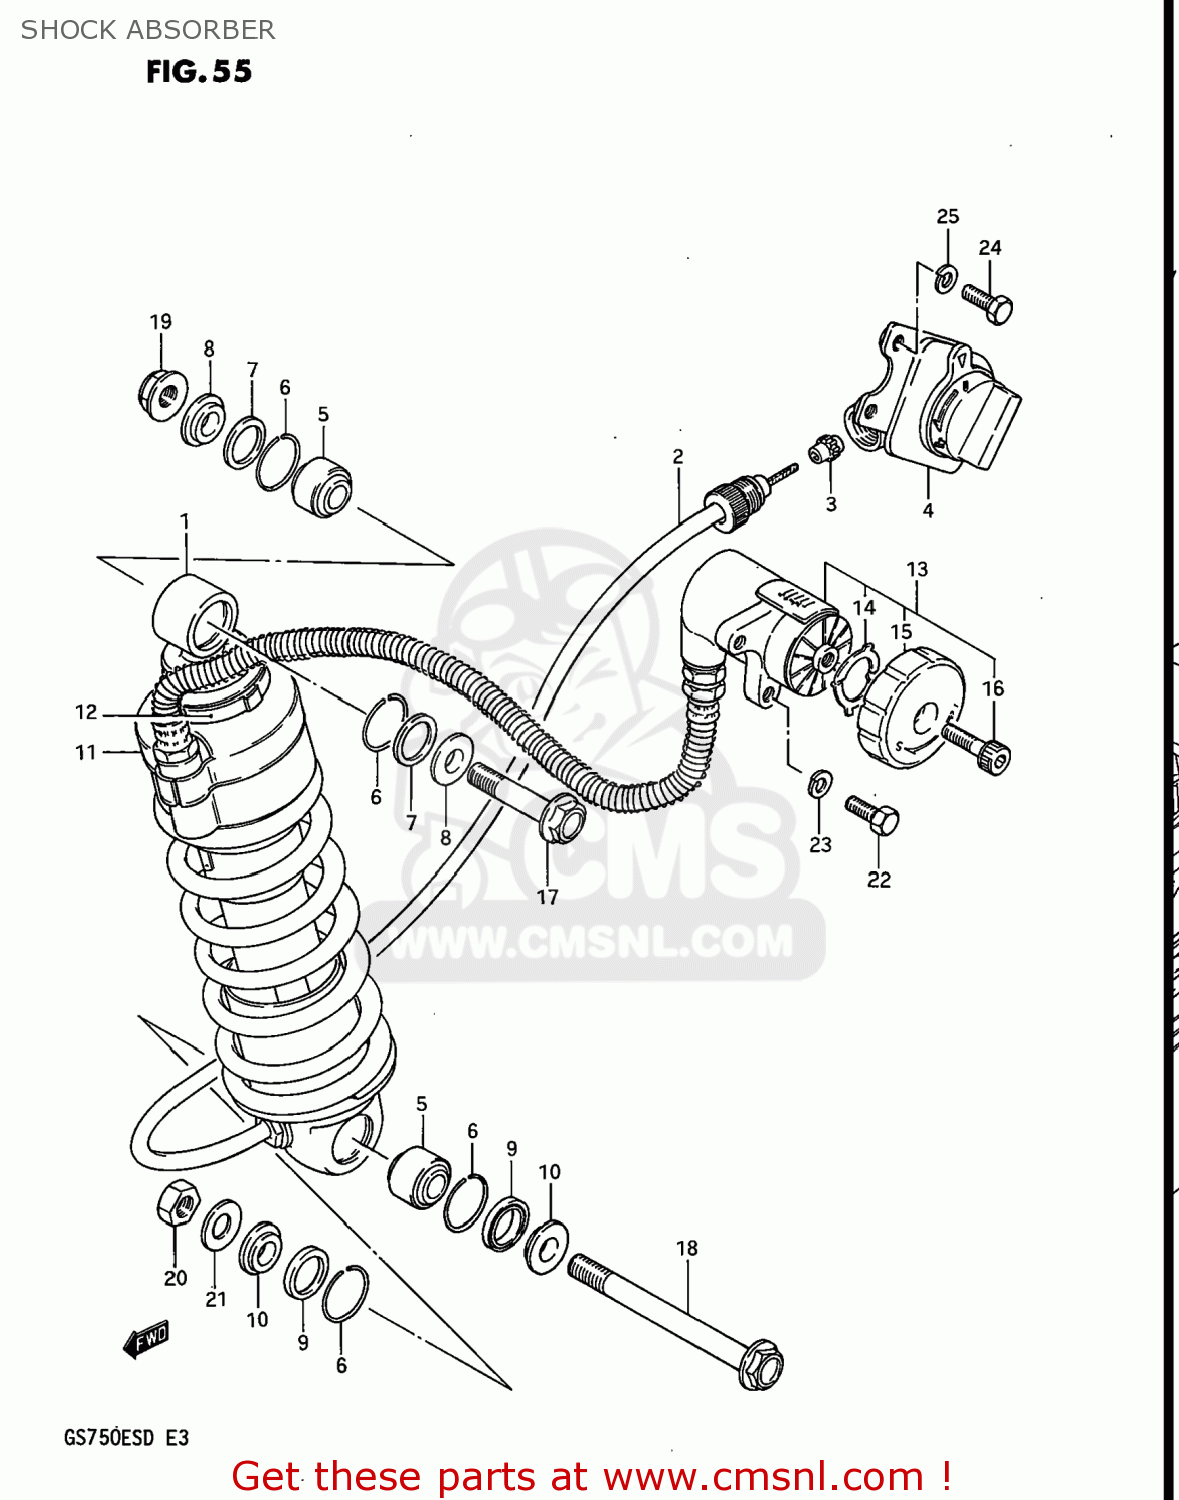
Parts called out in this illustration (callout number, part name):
1	ABSORBER ASSEMBLY,REAR SHOCK
2	CABLE,CONTROL
3	GEAR
4	ADJUSTER
5	BEARING
6	RING
7	DUST SEAL
8	SPACER
9	SEAL,DUST
10	COLLAR
11	COVER
12	BAND
13	CAM,DAMPER ADJUSTER
15	PLATE SET
16	PLATE,LEVELING
17	BOLT
18	BOLT(10X50)
19	BOLT(10X115)
20	NUT
21	NUT
22	WASHER
23	BOLT, UPPER
24	LOCK WASHER
25	BOLT, UPPER
26	LOCK WASHER
